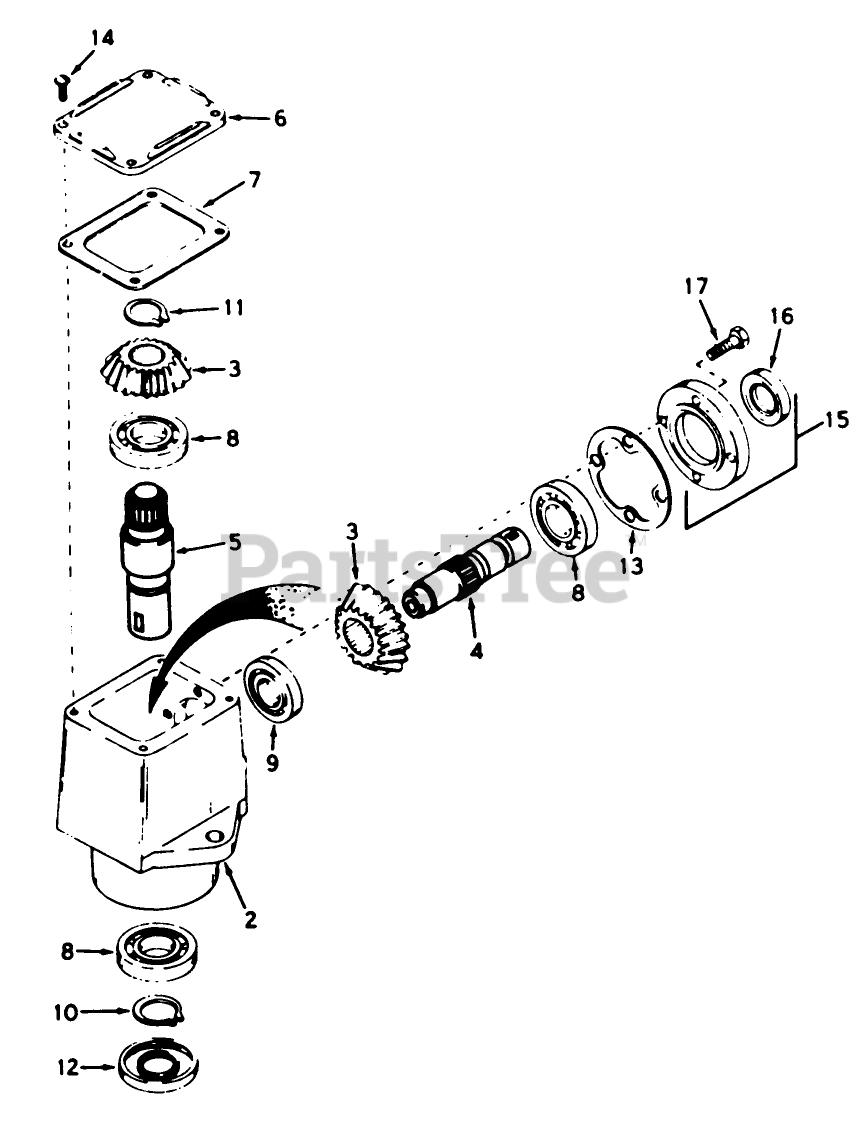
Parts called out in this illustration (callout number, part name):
2	Housing, Right Angle Drive
3	Bevel Gear
4	Shaft, Input
5	Shaft, Output
8	Bearing
9	Bearing
10	Ring-Snap
11	Ring-Snap
15	Cap and Seal Assembly, Retainer (Includes Nos. 16 17)
16	Oil Seal
17	Screw, Hex Hd., 1/4-10 x 1
